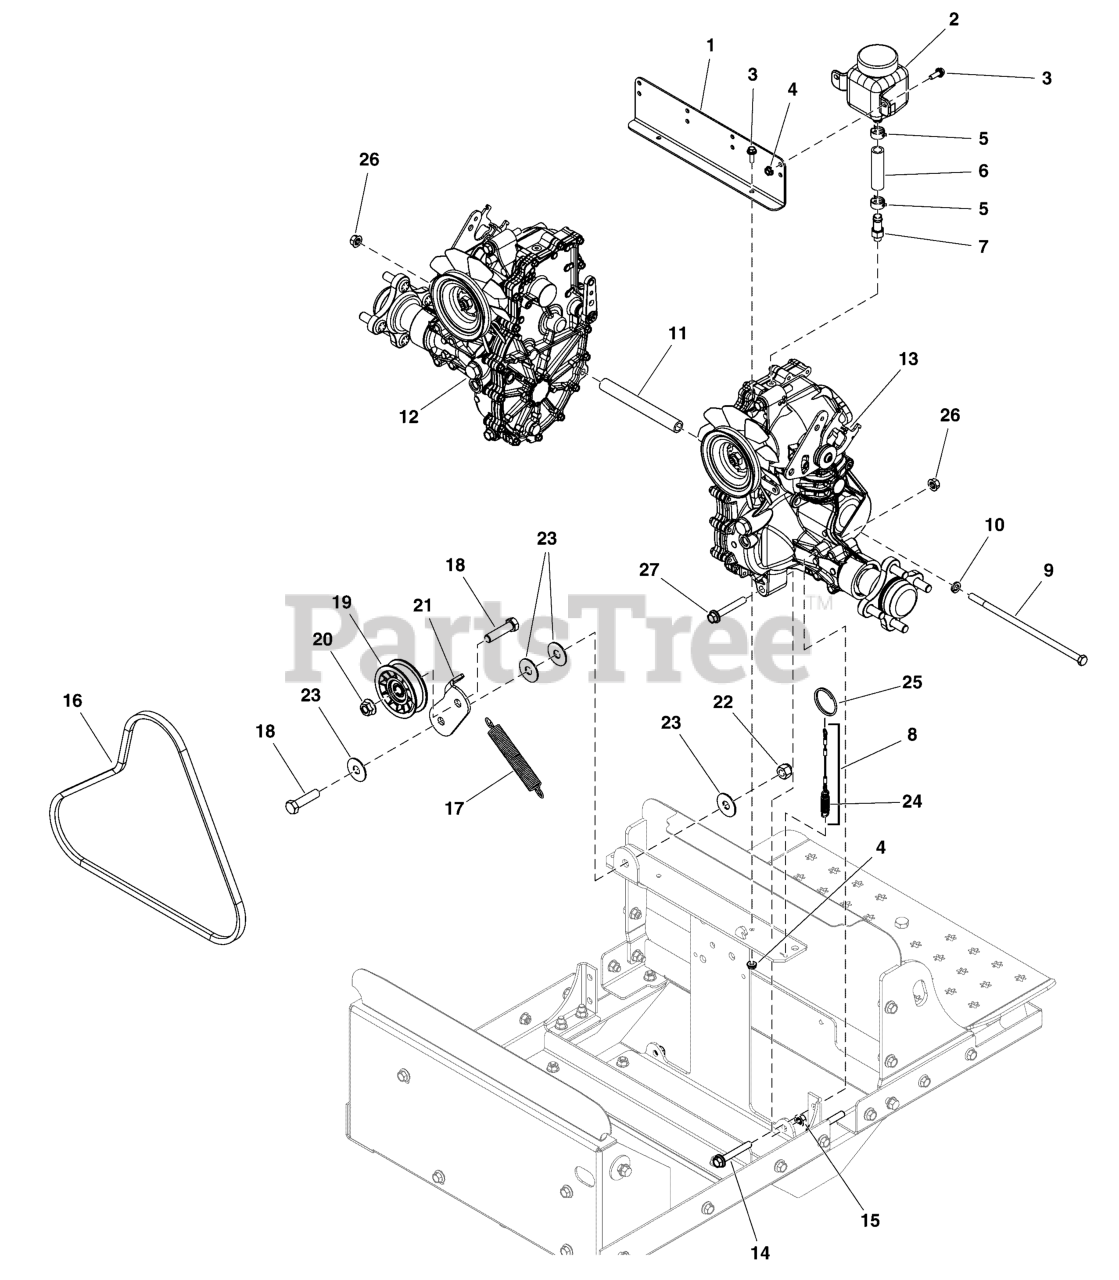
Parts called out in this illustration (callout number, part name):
1	MOUNT, OIL RESERVOIR - BLK
2	RESERVOIR, HYDRO OIL, 350 ML
3	BOLT, 1/4-20 X 3/4, FLANGE, CZ
4	NUT, 1/4-20 HEX SERR. FLANGE
5	CLAMP, HOSE, .75 FREE DIA.
6	HOSE, 1/2" PUSH-ON, 1.75"
7	FITTING, STRAIGHT 7/16-20 UNF
8	CABLE, HYDRO NEUTRAL RELEASE
9	BOLT, HEX, 3/8-16 X 10" GD 5, CZ
10	WASHER, 3/8 SAE
11	SPACER, .75 OD X 6.40 LONG, 10GA
12	TRANSAXLE, ZT3100, RH, ZJ-LCRP-3A7C-19XX
12	TRANSAXLE, ZT-3100, RH,ZJ-LCRP-SA7C-19XX
13	TRANSAXLE, ZT3100, LH, ZJ-HCRP-3A7B-19XX
13	TRANSAXLE, ZT-3100, LH,ZJ-HCRP-SA7B-19XX
14	BOLT, HEX, 3/8-16 X 3", SER FLG GRD5, CZ
15	NUT, 3/8-16, FLANGE, SERRATED UNDER HEAD
16	BELT, A-SEC, 47.15, RAW EDGE
17	SPRING, IDLER, #98
18	BOLT, 1/2-13 X 2" GD5 CZ
19	PULLEY IDLER 3.0 OD .506ID .75
20	NUT, Hex Flange, Nylock, 1/2-13
21	IDLER ARM - BLK
22	NUT, 1/2-13 HEX NYLON LOCK
23	WASHER, 0.54 X 1.50 X 0.060, CZ
24	SPRING, EXTENSION, #29
25	KEY RING, SPLIT 1"
26	NUT, 3/8 - 16 HEX NYLOCK FLANGE
27	BOLT, 3/8-16 X 2-1/2, FLANGE, CZ
